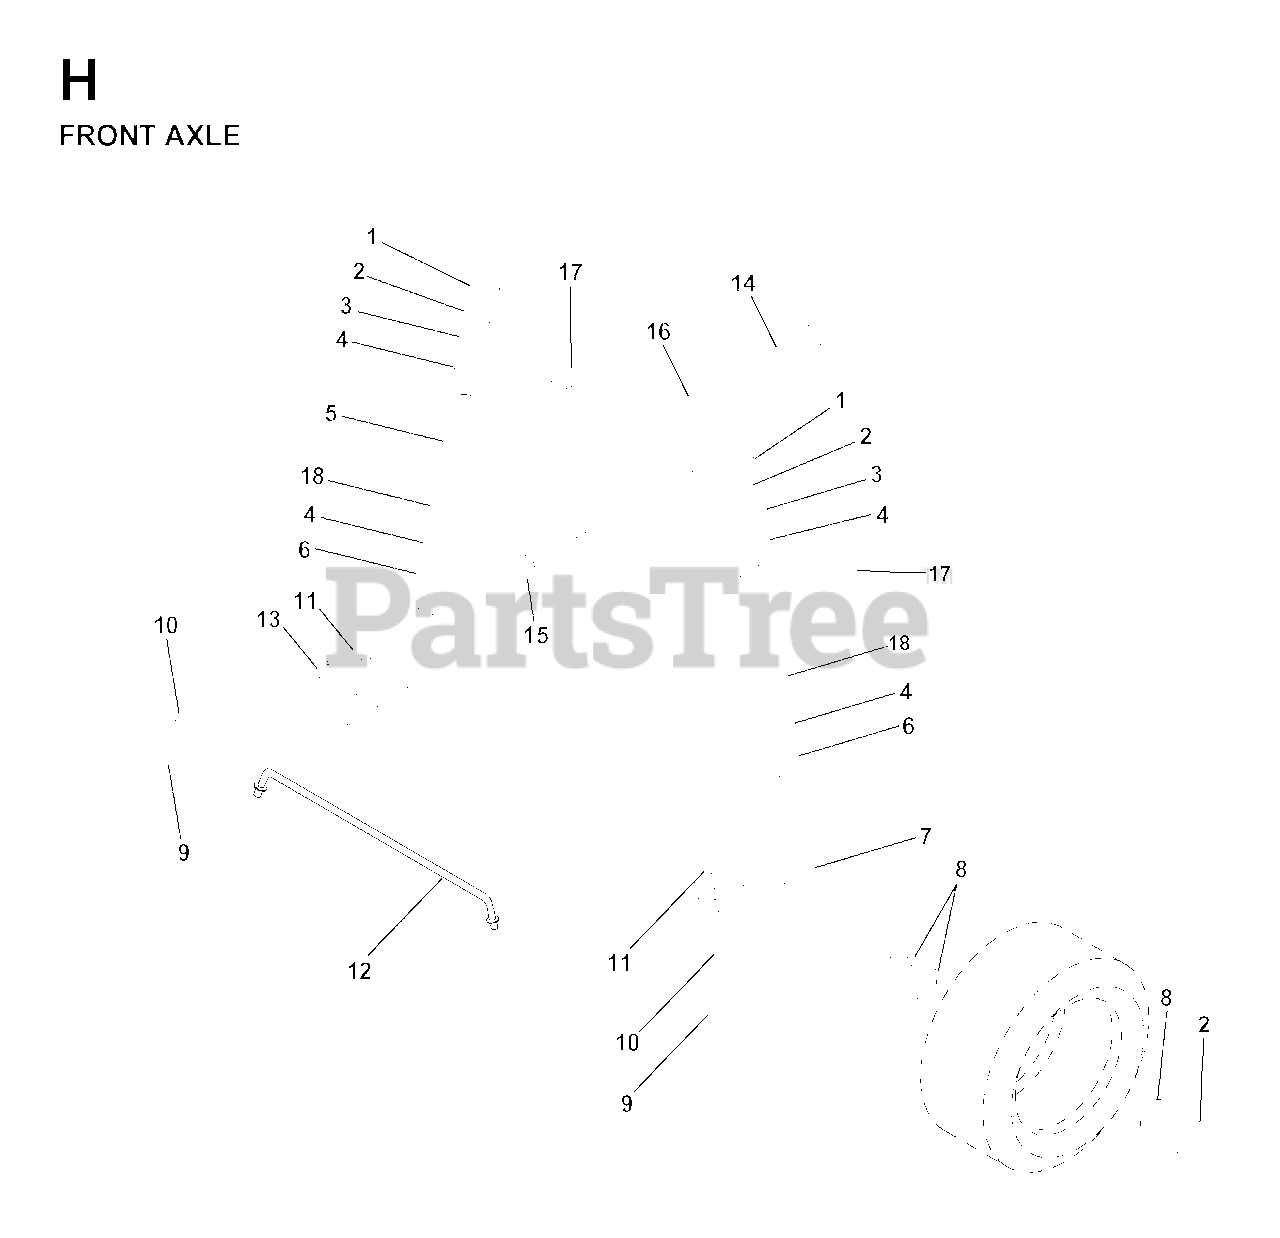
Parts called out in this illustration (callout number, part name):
1	CAP.SPINDLE
2	RING CLIP
4	BRNG T
5	AXLE ASSY
9	COTTER PIN
11	BUSHING.DRAGLINK
12	TIE ROD
13	SPINDLE.ASSEM.LH
14	BOLT.HEX.5/8-11
15	NUT-LOC,FLANGE LT
16	BEARING
17	ZERK M
